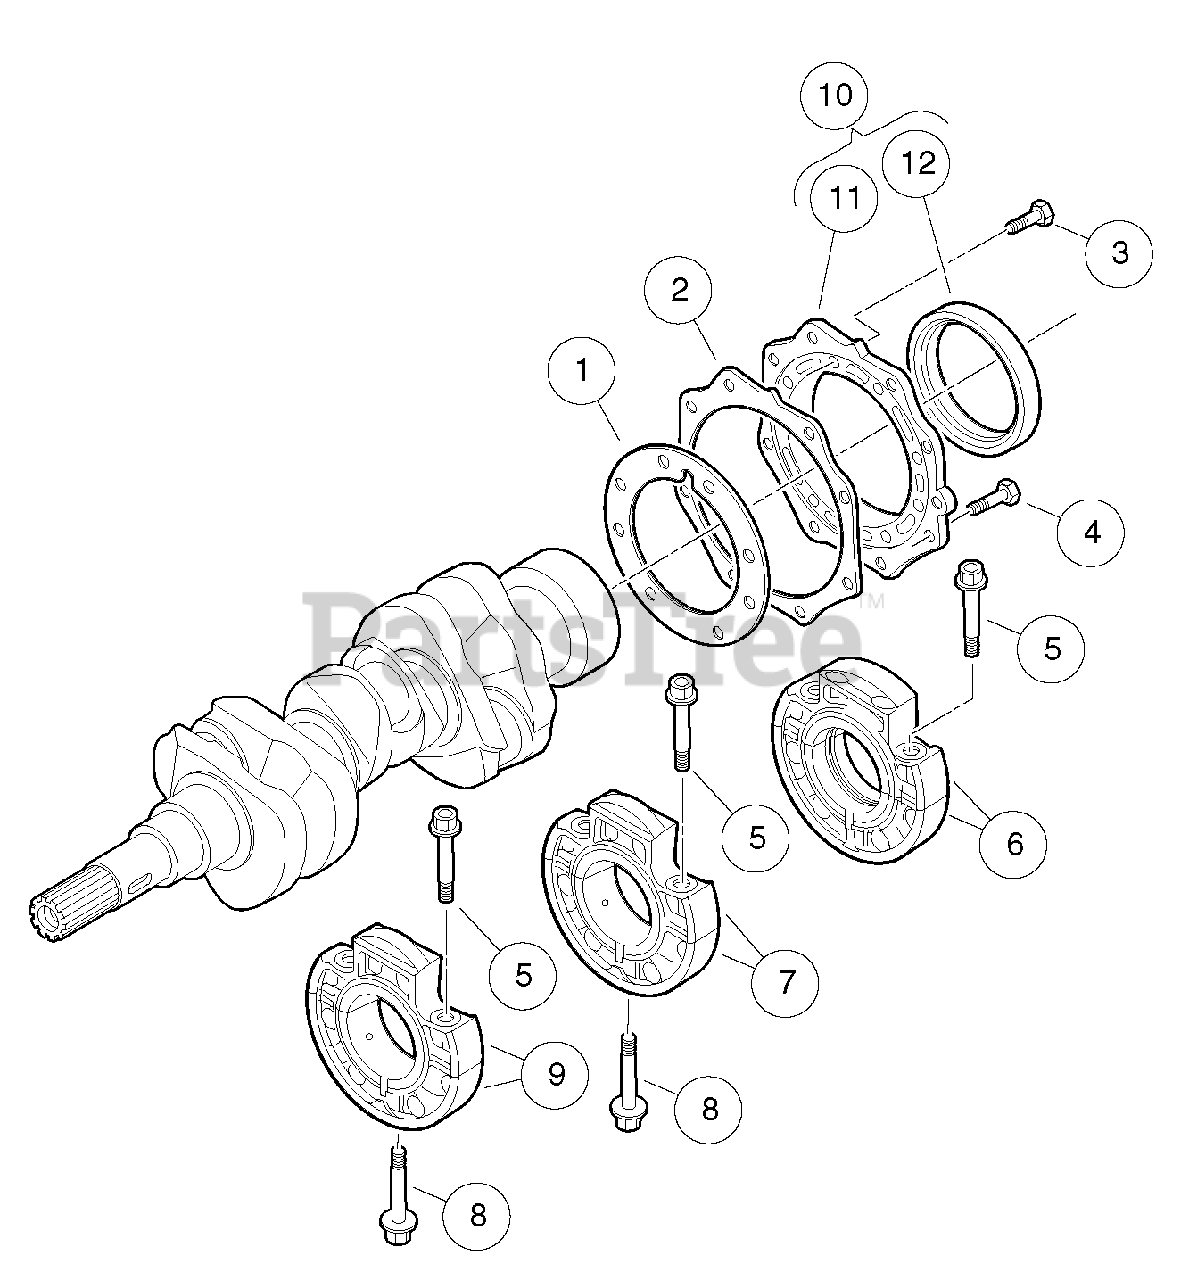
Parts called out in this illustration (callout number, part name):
1	Gasket, Bearing Case
2	Gasket, Cover
3	Bolt, M6 X 1 X 20
4	Bolt, M6 X 1 X 22
5	Bolt, Bearing Case, Top
6	Assy Case, Main Brg, First
7	Assy Case, Main Brg, Sec
8	Bolt, Bearing Case, Bottom
9	Assy Case, Main Brg, Third
10	Assy, Cover, Bearing Case
11	Cover, Bearing Case
